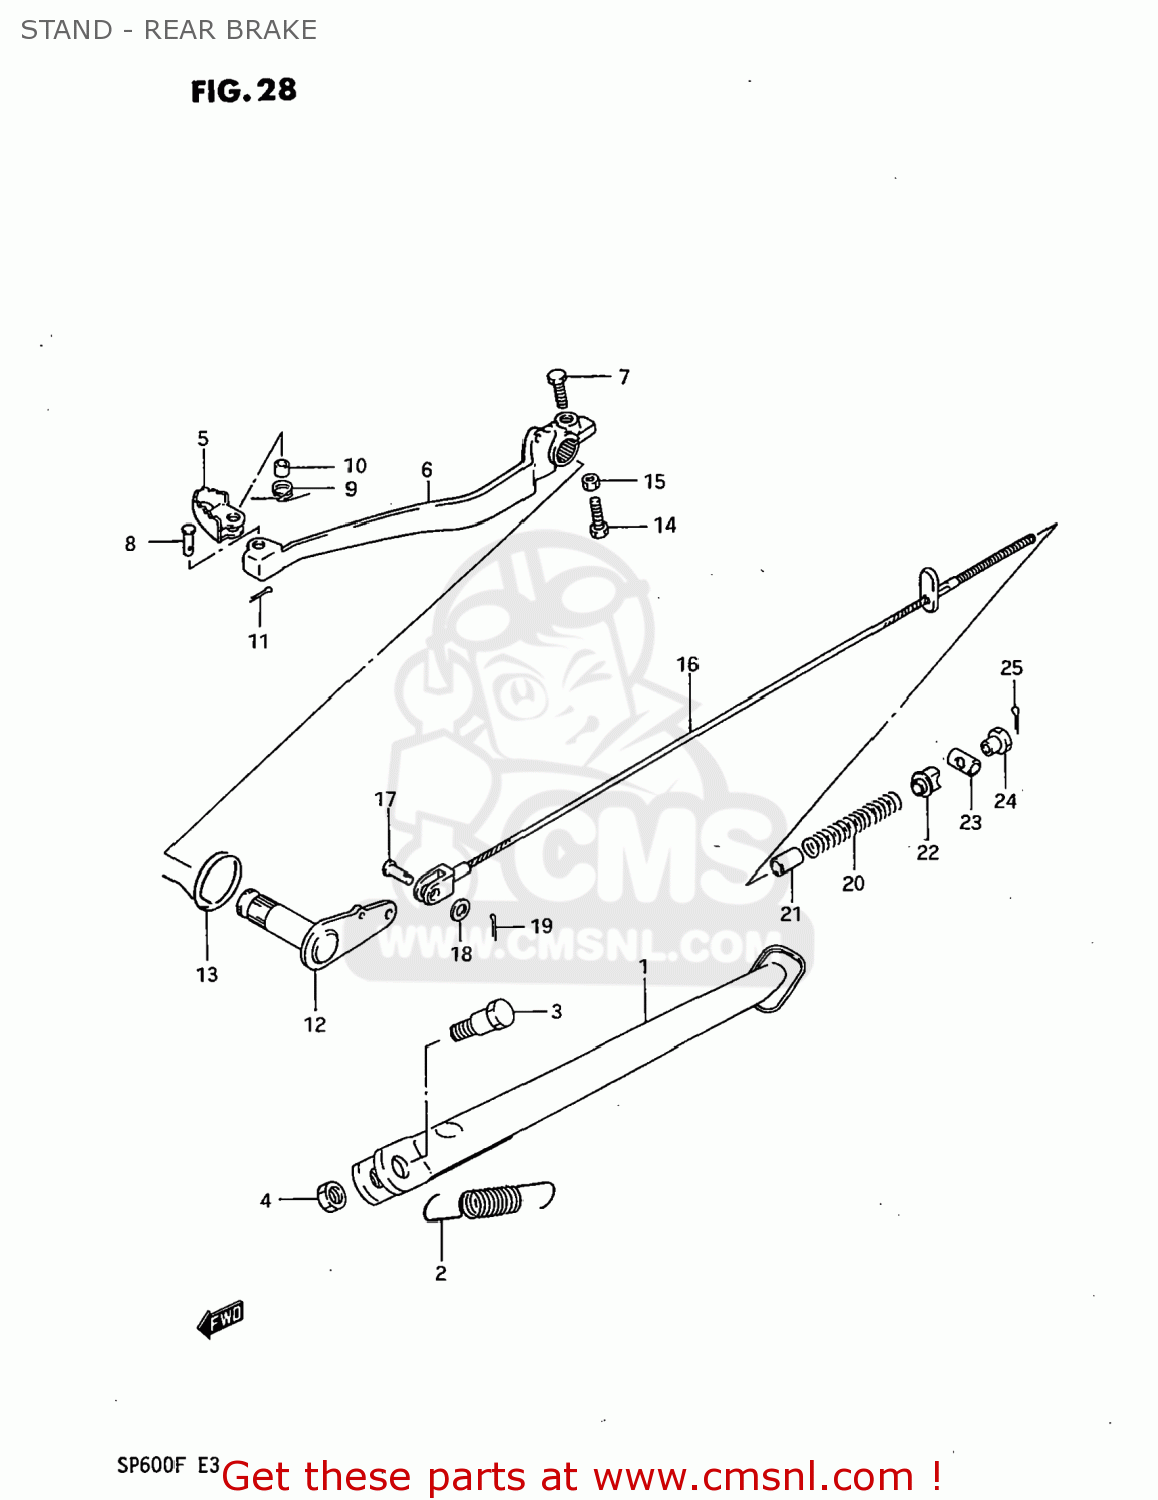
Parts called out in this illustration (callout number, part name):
1	STAND,SIDE
2	SPRING
3	BOLT L:30
4	NUT
5	PEDAL,BRAKE
6	ARM,BRAKE PEDAL
7	BOLT
8	PIN
9	SPRING
10	SPACER(9.2X9X6.5)
11	PIN
12	ARM,BRAKE PEDAL ROD
13	SPRING
14	BOLT(6X23)
15	NUT
16	CABLE,RR BRAKE
17	PIN(L:17.5)
18	WASHER, LOWER
19	PIN
20	SPRING
21	CUSHION,FR GRILLE,UPPER
22	CUSHION
23	PIN,BRAKE CABLE ADJUSTER
24	NUT (6MM)
25	PIN
